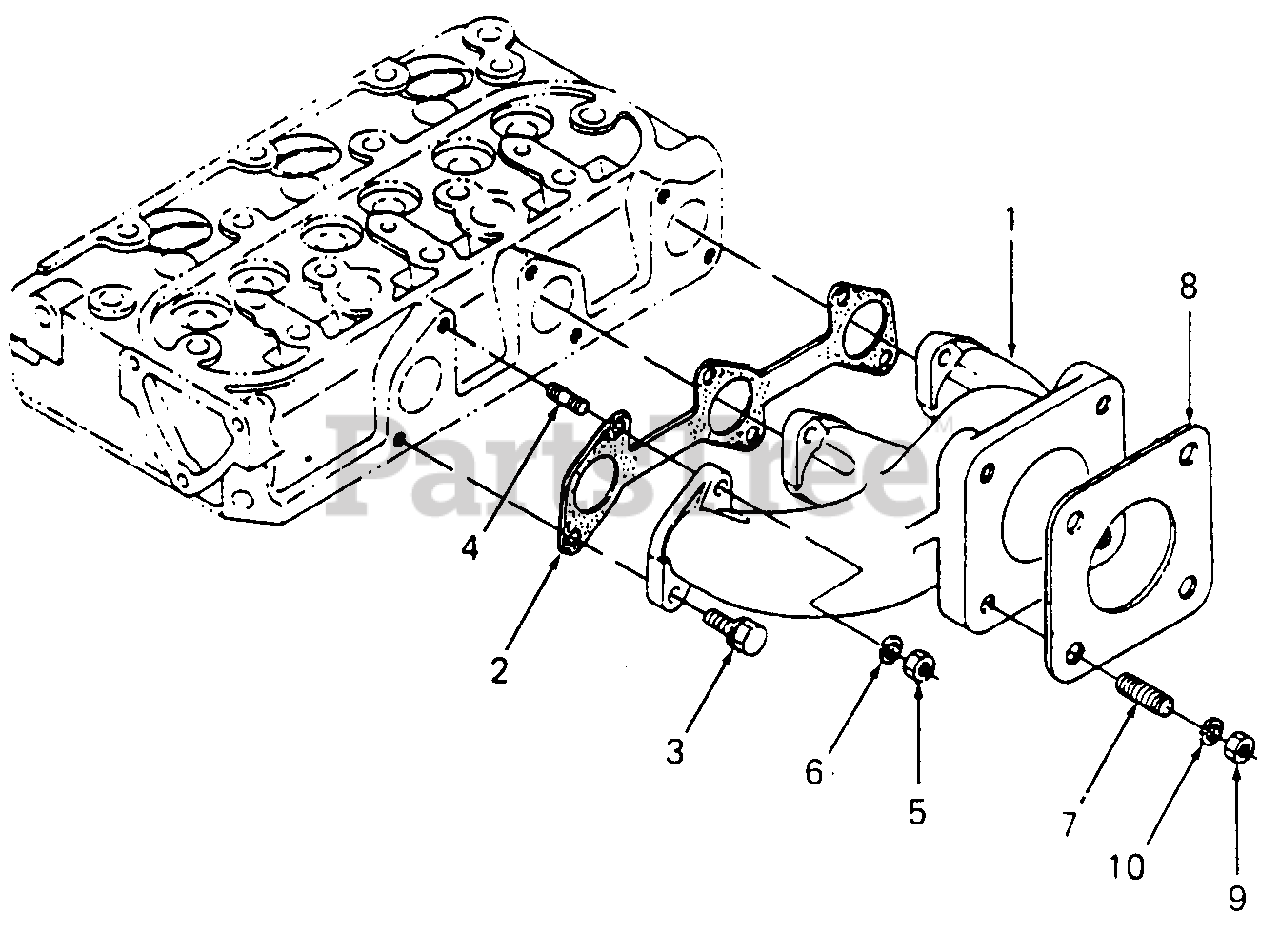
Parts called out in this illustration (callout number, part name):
1	Manifold, Exhaust
2	Gasket, Exhaust Manifold
6	Washer, Spring
8	Gasket, Muffler
10	Washer, Spring
